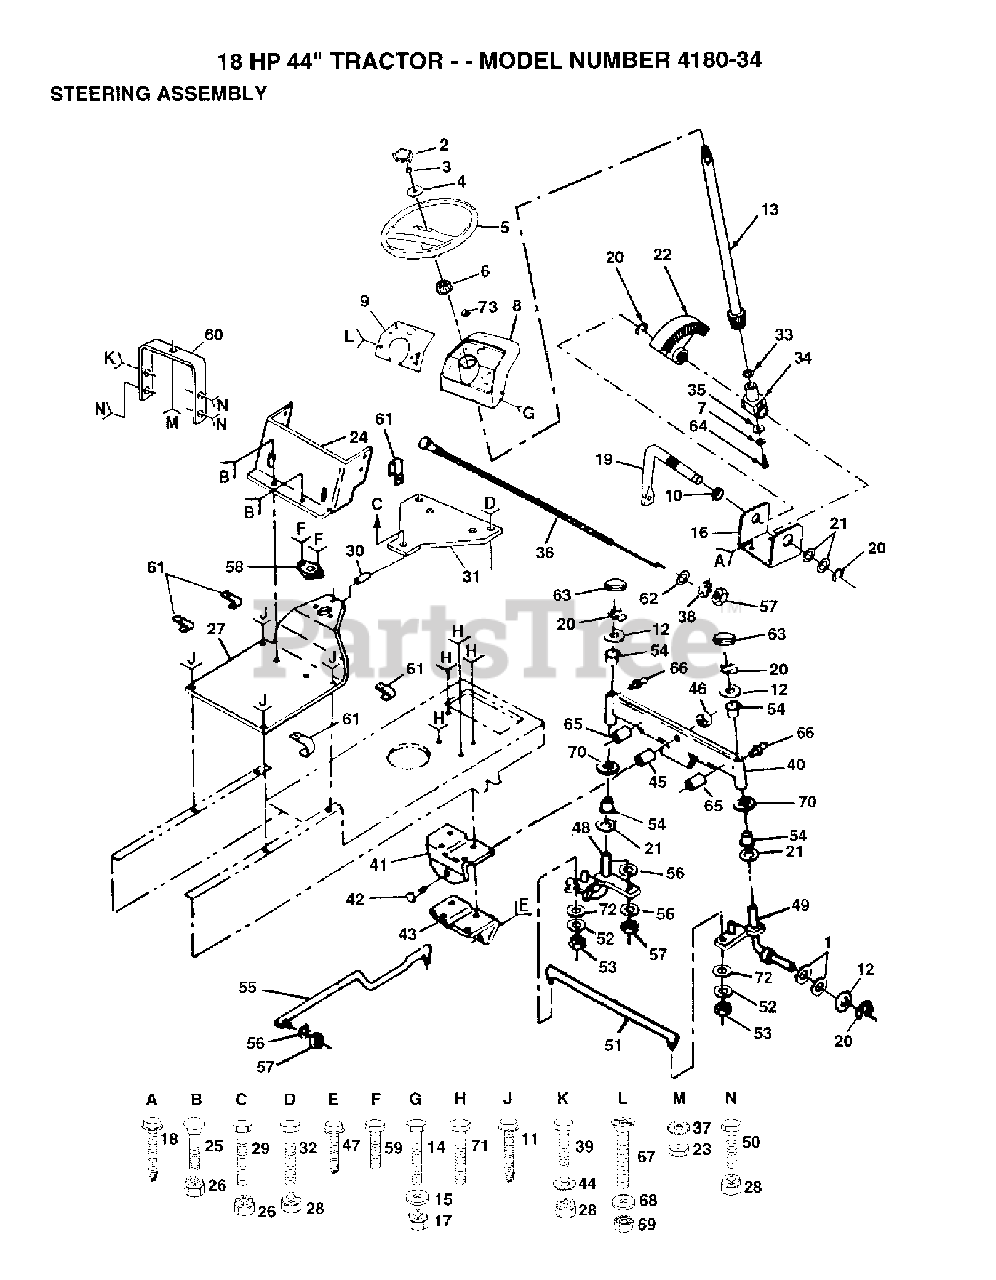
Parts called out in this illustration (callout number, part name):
2	INSERT STR WHL
3	NUT.HEX.1/2-20
5	Steering Wheel
7	LOCKWASHER
10	NYLINER T (7283A)
11	SCREW LT
13	SHAFT ASS'Y STEER
14	BOLT
15	WASHER
16	BRKT,STEERING
17	LOCKNUT
19	SHAFT,PITMAN
20	RING CLIP
21	WASHER THRUST
22	GEAR.SECTOR
23	NUT
24	DASH LOWER YT NLA
26	LOCKNUT
28	LOCKNUT
31	PLATE SUPPORT T NLA
33	THRUST WASHER
34	SHAFT,SUPPORT
35	WASHER
36	CONTROL CHOKE
37	LOCKWASHER
38	LOCKWASHER
39	BOLT
40	AXLE ASSY T
41	SUPPORT-SADDLE LT NLA
43	SUP-SADDLE FRT LT
44	LOCKWASHER
46	LOCK NUT
47	SCREW LT
52	LOCKWASHER
53	LOCKNUT
54	BEARING.STEERING.COLUMN
55	DRAG LINK
56	WASHER, LOCK 3/8
57	NUT
58	BUSHING
59	SCREW LT
60	SUPPORT ASS'Y
61	CLIP T
63	CAP.SPINDLE.BLACK
66	ZERK.GREASE.TAPERED
68	WASHER
71	SCREW SPECIAL
72	WASHER M
73	PLUG-DASH T
